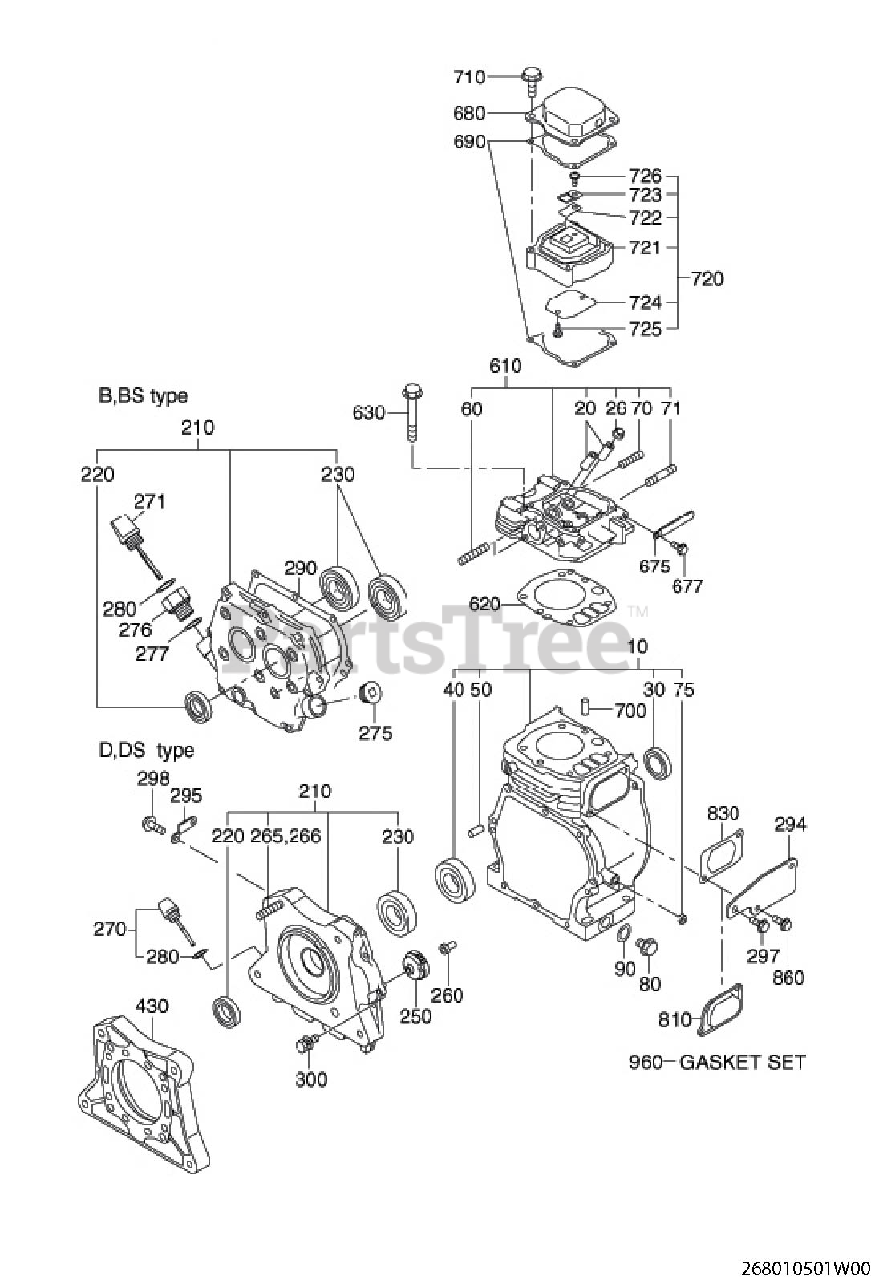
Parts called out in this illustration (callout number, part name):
10	CRANK CASE CP
20	VALVE GUIDE
26	STEM SEAL
30	OIL SEAL
40	BALL BEARING
50	DOWEL PIN
60	STUD
70	STUD
75	OIL SEAL
80	PLUG
90	GASKET
210	MAIN BEARING COVER C
220	OIL SEAL
230	BALL BEARING
250	GOVERNOR GEAR CP
260	GOVERNOR SLEEVE
266	STUD
280	GASKET
294	BRACKET(M.B.C) CP
295	SUPPORT(M.B.C)
297	BOLT AND WASHER AY
298	BOLT AND WASHER AY
300	BOLT AND WASHER AY
610	CYLINDER HEAD CP
620	GASKET (HEAD)
630	FLANGE BOLT
675	CLAMP
677	FLANGE BOLT
690	GASKET(ROCKER COVER)
700	DOWEL PIN
710	FLANGE BOLT
720	SPACER(BREATHER) AY
721	SPACER(BREATHER)
723	RETAINER PLATE
725	FLANGE BOLT
726	SCREW AND WASHER AY
830	GASKET(BREATHER CVR)
860	BOLT AND WASHER AY
